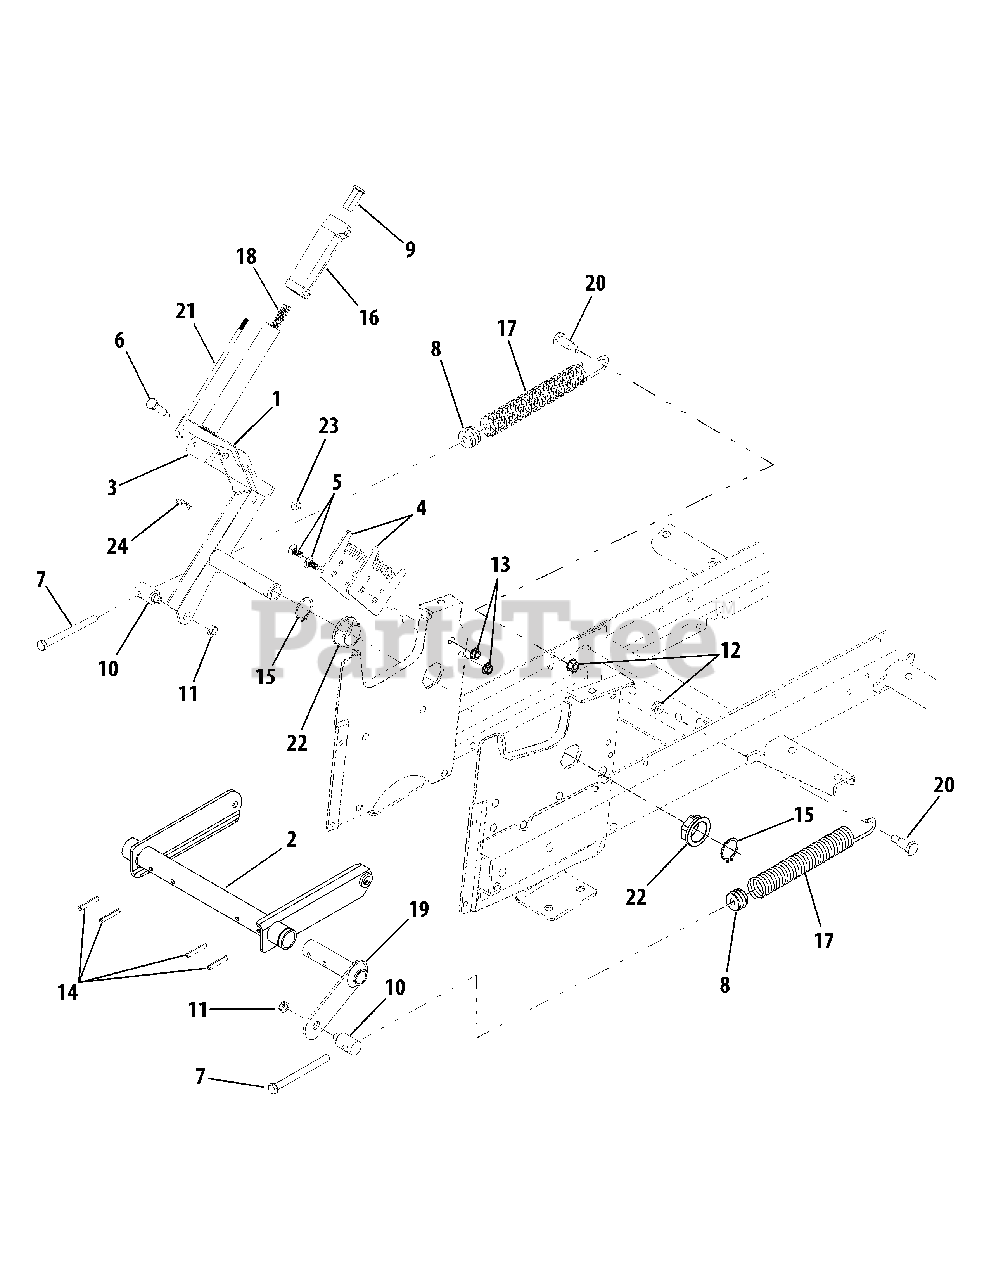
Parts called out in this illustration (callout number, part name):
1	Handle Assembly, Lift
2	Shaft Assembly, Lift
4	Bracket, Lift Index
5	Bolt, Carriage, 5/16-18 x .75
6	Screw, Hex Cap, 3/8-16 x 4.25 GR5
7	Insert, Spring
8	Button, Handle
9	Ferrule, Adjustment
10	Nut, Hex Center Lock, Jam, 3/8-24
11	Nut, Hex Flanged Top Lock, 5/16-18
12	Nut, Hex Flange Lock, 1/4-20
13	Pin, Internal Cotter
14	Pin, Spiral Spring, 1/4 Dia x 1.5
15	Ring, Snap, 1.25 Dia Shaft
16	Grip, Lift Handle
17	Spring, Extension
18	Spring, Compression
19	Bolt, Shoulder
20	Screw, Shoulder, .374 x 1.375
21	Rod, Index
22	Bearing, Hex Flange
